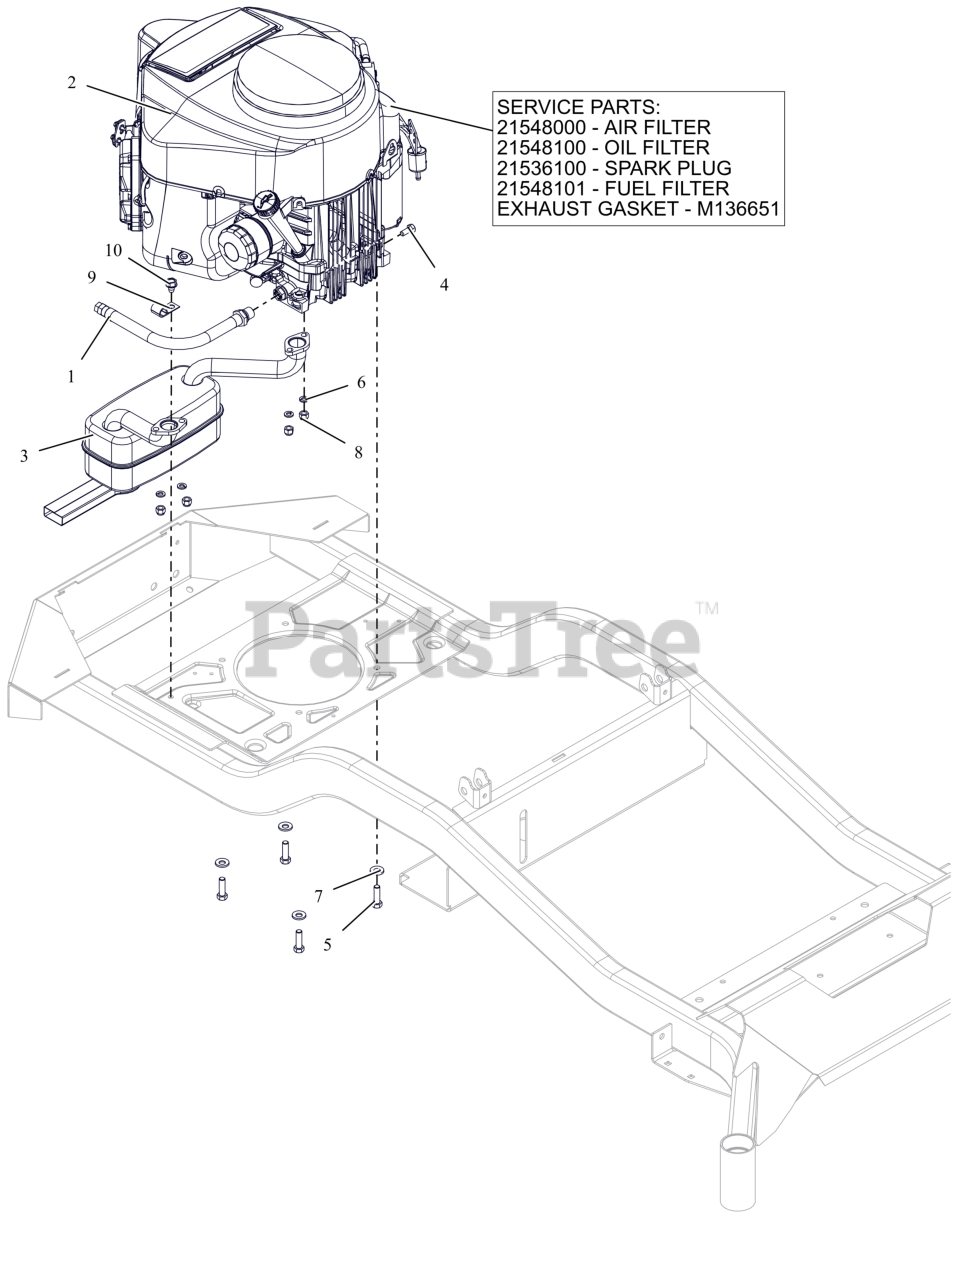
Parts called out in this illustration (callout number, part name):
1	HOSE, OIL DRAIN
2	ENGINE, KAWASAKI FR691 23HP
2	AIR FILTER, KAWASAKI FR
2	OIL FILTER, KAWASAKI FR
2	PLUG, SPARK
2	FUEL FILTER-KAWASAKI FR
2	GASKET, MUFFLER #
3	MUFFLER, KAWASAKI
4	BLT, HEX M8-1.25X20 G8.8 ZCC
5	BLT, HEX .38-16X1.25 G5 ZCC NT
6	WSHR,LK-REG .312X.078 ZCC
7	WASHER, 3/8" SPRING DISC
8	NUT, LK-CTR-JAM M8-1.25 GR8.8 ZC120
9	J-CLAMP
10	SCR,TAP .375-16X.50 HWH TR ZCC
